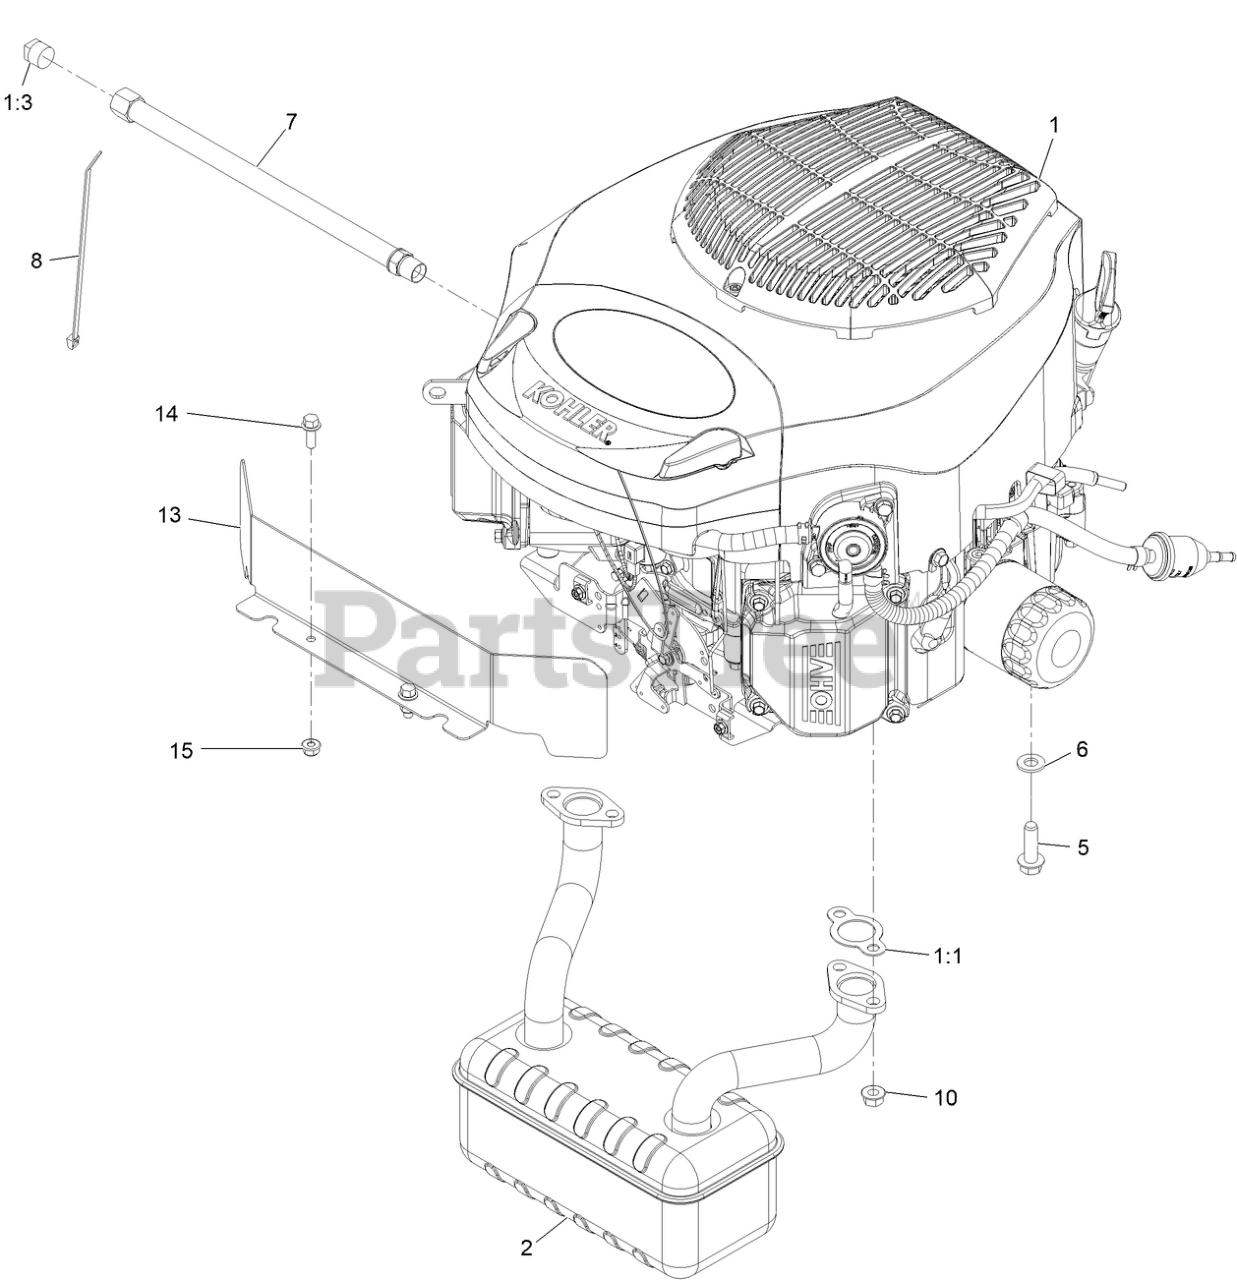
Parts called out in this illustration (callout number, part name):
1:1	GASKET-EXHAUST
2	Muffler
5	SCREW-THD
6	WASHER-FLAT
7	HOSE-DRAIN, OIL
8	TIE-CABLE
13	SHIELD-HEAT
14	Screw-HHF
15	SCREW-SHOULDER
